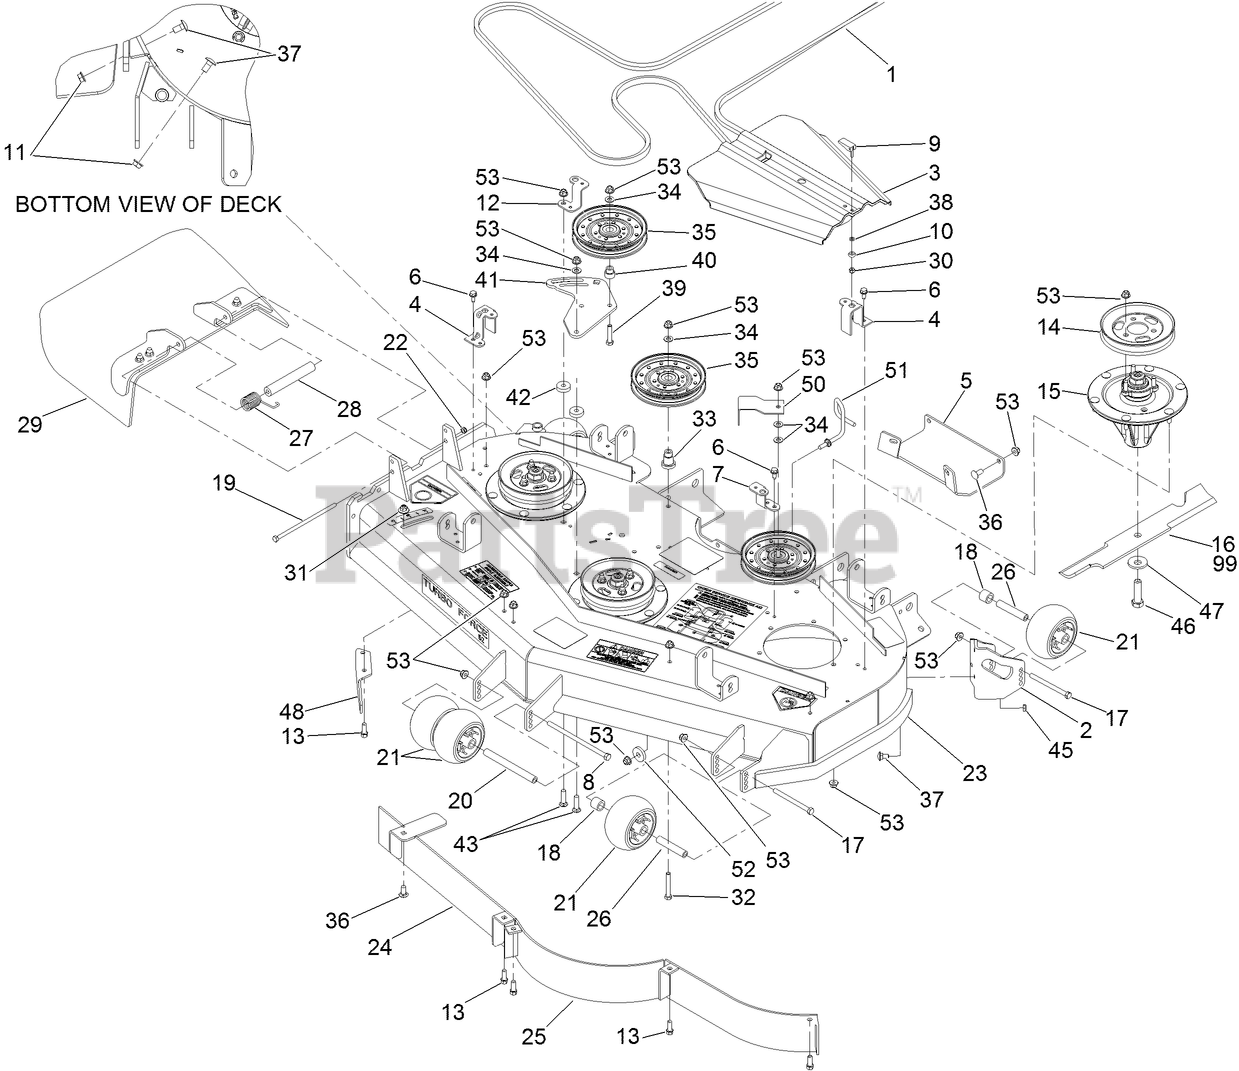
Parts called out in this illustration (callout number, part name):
2	MOUNT-WHEEL, LH
3	COVER-BELT
4	BRACKET-COVER
5	Plate-Skid
6	SCREW-HWHTF
7	BRACKET-COVER, TALL
8	SCREW-HH
9	HANDLE-LATCH, SWELL
10	BUSHING-LATCH, SWELL
11	NUT-HHF, WHIZ
12	BRACKET-COVER, SHORT
13	SCREW-HWH
14	Pulley
15	SPINDLE ASM
16	BLADE-18IN, HI FLOW
17	SCREW-HH
18	TUBE-SPACER
19	SCREW-HH
20	SPACER-WHEEL
21	ROLLER-SCALP, ANTI
22	NUT-LOCK, NI
23	DECK DECAL ASM
24	BAFFLE ASM
26	TUBE-SPANNER
27	SPRING-TORSION
28	SPACER
29	RUBBER DEFLECTOR ASM
30	NUT-LOCK, HH
31	NUT-FLANGE, NI
32	SCREW-HH
33	MOUNT-PULLEY
34	WASHER-FLAT
35	Idler-Flat
36	SCREW-CARR
37	SCREW-CARR
38	WASHER
39	SCREW-HH
40	BUSHING-IDLER
41	PLATE-IDLER
42	Spacer
43	SCREW-CARR
45	NUT-LOCK, NI
46	SCREW-BLADE
47	Washer-Blade Bolt, Heavy
48	BAFFLE-DISCHARGE
50	GUIDE-BELT
51	GUIDE-BELT
52	WASHER
53	NUT-HF, NI
99	BLADE-ATOMIC
99	BLADE-LOW FLOW
99	BLADE-MED FLOW
99	BLADE-RECYCLER
